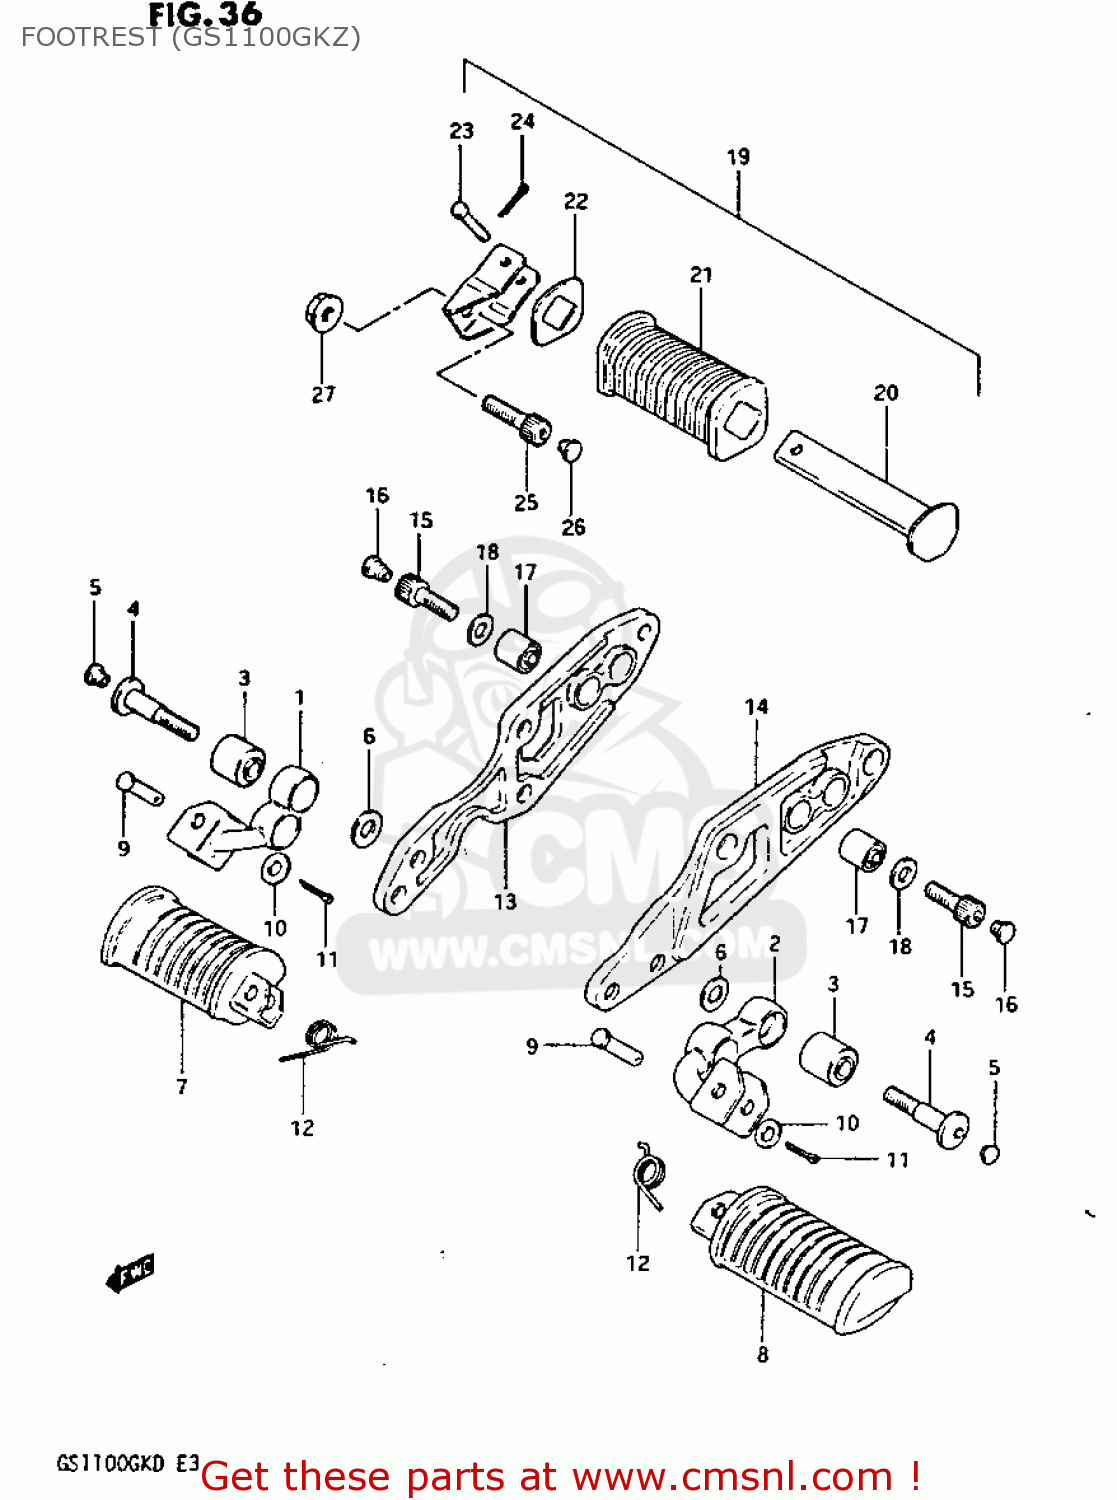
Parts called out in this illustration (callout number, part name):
1	BAR,FRONT FOOTREST,RIGHT
2	BAR,FRONT FOOTREST,LEFT
3	BUSH
4	BOLT(10X50)
5	CAP
6	WASHER (10X18X3.2)
7	RUBBER,FRONT FOOTREST
8	FOOTREST
9	PIN
10	WASHER
11	PIN 20X20
12	SPRING
13	BRACKET,MUFFLER,RIGHT
14	BRACKET,MUFFLER,LEFT
15	BOLT
16	CAP
17	BUSH
18	WASHER(10.5X20X3.2)
19	FOOTREST ASSEMBLY,REAR,LEFT
20	BAR,REAR FOOTREST
21	RUBBER,RR FOOTREST
22	WASHER,RR FOOTREST RUBBER
23	PIN
24	PIN 20X20
25	BOLT, (10X30)
26	CAP
27	NUT
